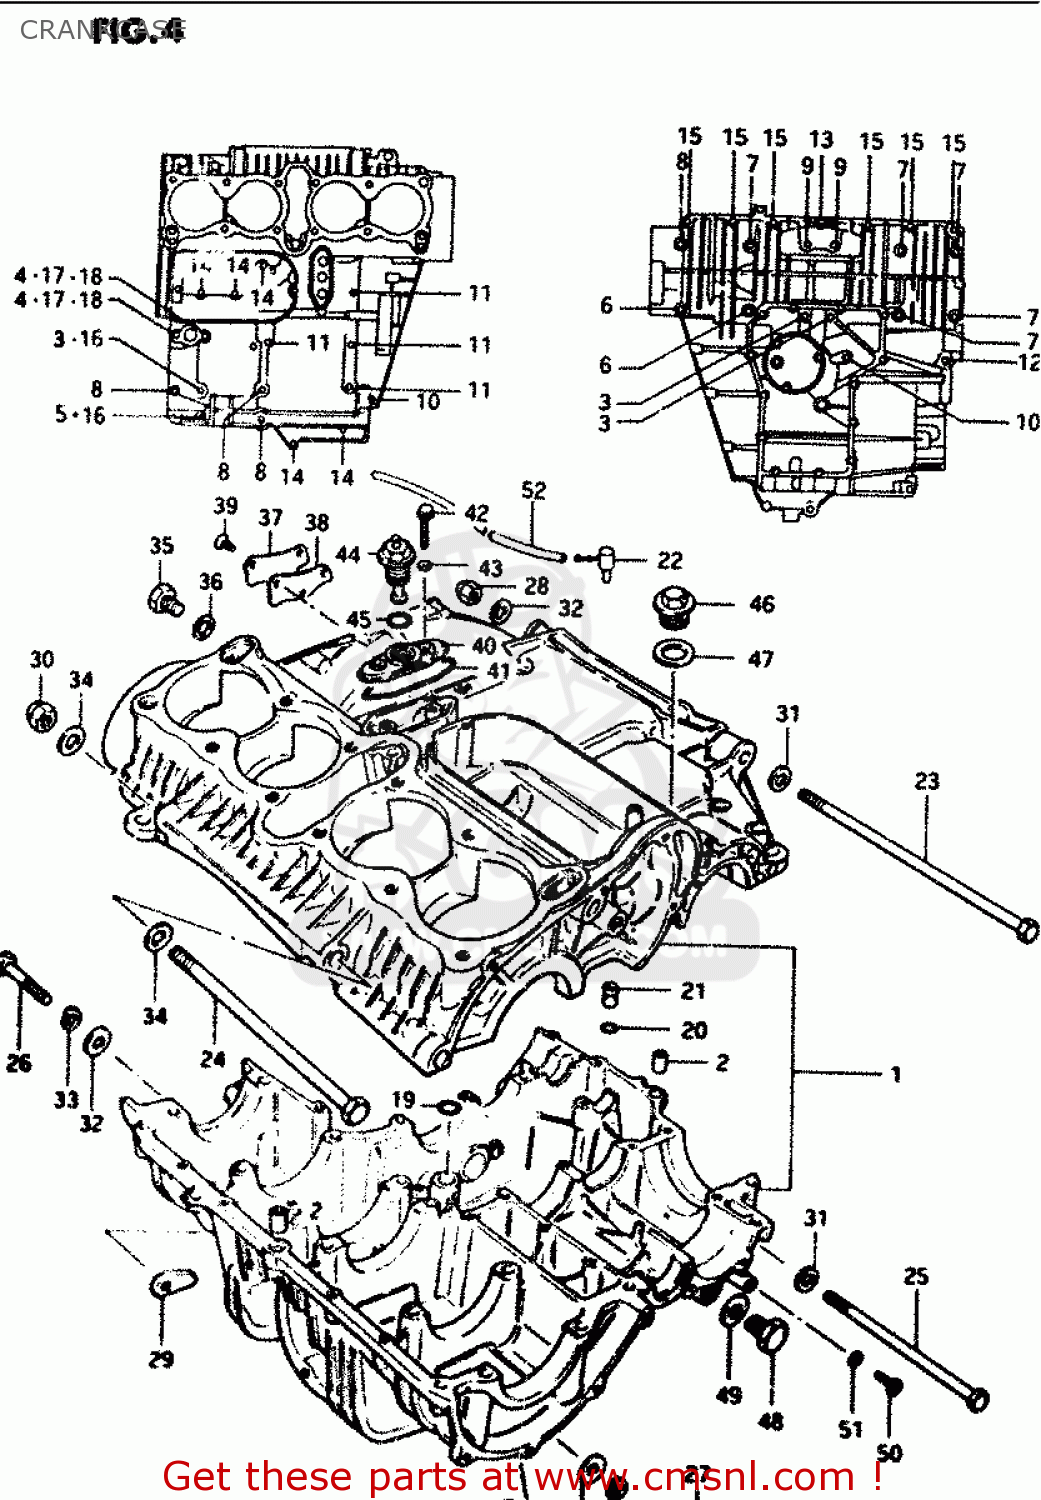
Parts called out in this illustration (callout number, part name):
1	CRANKCASE SET
2	PIN
3	BOLT
4	BOLT 8X110
5	BOLT
6	BOLT
7	BOLT (8X90)
8	BOLT (8X65)
9	BOLT 8X60
10	BOLT (6X90)
11	BOLT (6X75)
12	BOLT 6X55
13	BOLT 6X50
14	BOLT (6X45)
15	BOLT 6X35
16	NUT 8MM
17	NUT
18	GASKET 8.2X14X1 (NAS)
19	O RING(D:3.2,ID:12.9)
20	O RING(D:1.05,ID:3.1)
21	UNION
22	BPLUG,BEVEL GEAR BREATHER
23	BOLT
24	SHAFT,REAR SWING ARM
25	BOLT
26	BOLT (10X60)
27	BOLT (10X50)
28	NUT (10MM)
29	NUT
30	NUT
31	WASHER (10.5X20X3.2)
32	WASHER
33	LOCK WASHER
34	WASHER
35	PLUG (14X12)
36	GASKET(14X19.2X2) (NAS)
37	CAP,OIL GALLERY
38	GASKET,OIL GALLERY (MCA)
39	SCREW
40	HOUSING,OIL PRESSURE SWITCH
41	O RING,PRESSURE SWITCH HOUSING
42	BOLT
43	WASHER
44	SWITCH ASSEMBLY
45	O RING(D:1.9,ID:18.8)
46	PLUG
47	GASKET
48	PLUG
49	GASKET(14X19.2X2) (NAS)
50	SCREW(6X10)
51	WASHER
52	HOSE
